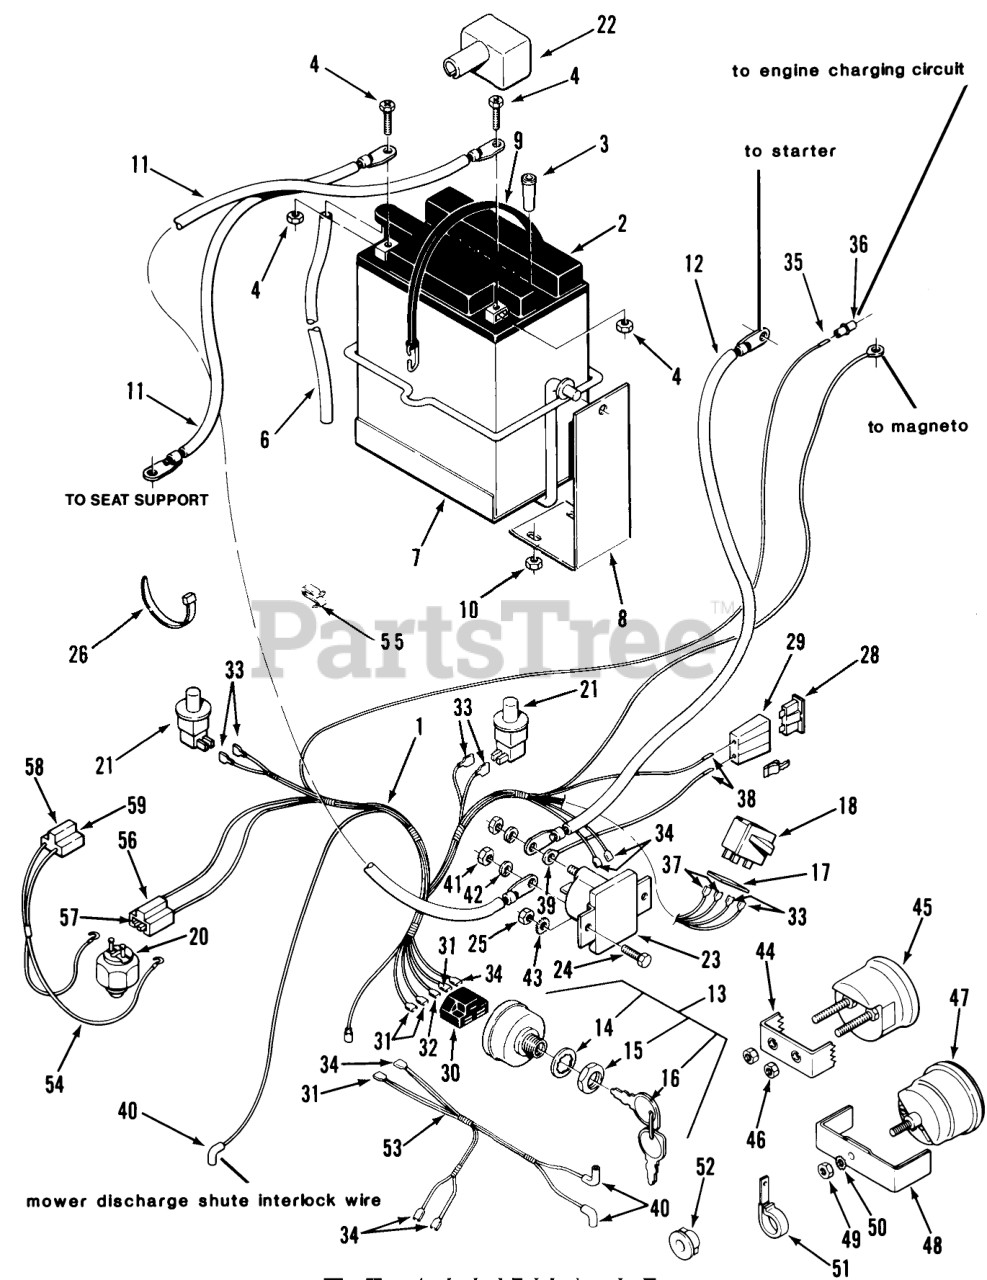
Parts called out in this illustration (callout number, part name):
1	WIRING HARNESS
2	BATTERY 120CCA
3	ADAPTER
4	ASSY BATTERY HDW
6	HOSE BATTERY DRAIN
7	BATTERY TRAY B
8	BRACKET B
9	STRAP
10	Nut
11	ASSY WIRE
12	WIRE ASM
13	Ignition Switch Ass-y
14	LOCKWASHER
16	Ignition Key
16	KEY PADDED
17	SHIELD-DIRT (DPDT)
18	PTO Interlock Switch
20	SWITCH (N.C.-TRANS)
21	SWITCH (N.C.)
22	COVER-TERMINAL
23	Solenoid
24	Screw
25	Nut
26	PLASTIC TIE
28	FUSE-BLADE, 15 AMP
29	AUTO-FUSEBLOCK TERM
30	CONNECTOR-5 WAY-SERV
31	Terminal
32	TERMINAL-TAB RCPT
33	Terminal
34	Connector
35	Terminal
36	SOCKET HOUSING
37	Wire Terminal (Part of 1)
38	TERMINAL-FUSE
39	Wire Terminal (Part of 1)
40	Terminal Part of 5
41	Nut
42	Washer
43	LOCKWASHER
44	CLAMP MOUNTING
45	Voltmeter (w/109650)
46	HEX NUT 10-32 E.S.
47	Hourmeter 314, 417
48	HOUR METER CLAMP
49	Hex Nut
50	Lockwasher
51	CLAMP
52	BUSHING-NYLON .75
53	Volt & Hourmeter Harness
54	ASSY WIRING HARNESS
55	SPEED CLIP
56	WHEEL ASM
57	Connector Part of 5
58	CONNECTOR BODY B
59	TERMINAL-TAB RCPT
